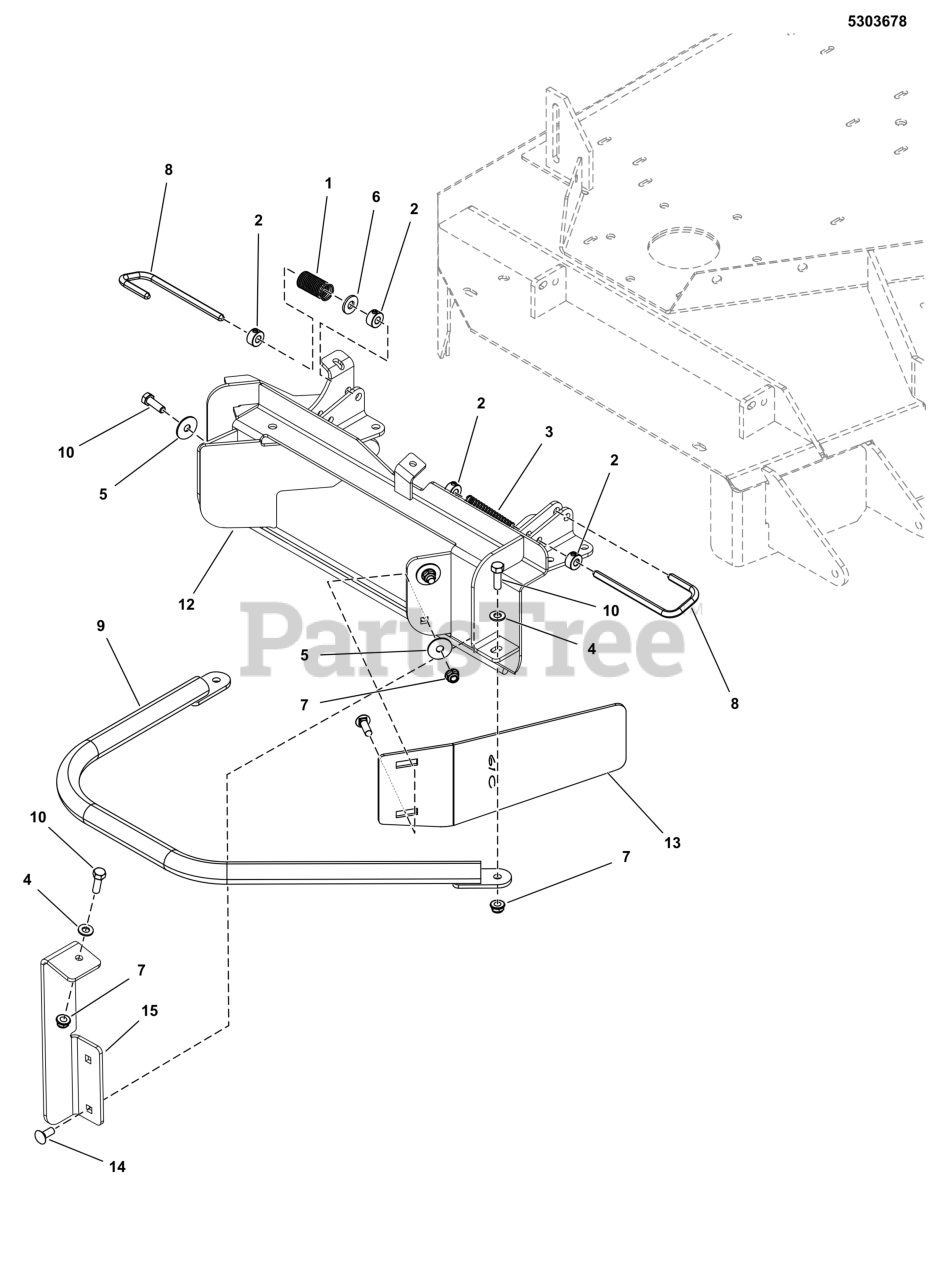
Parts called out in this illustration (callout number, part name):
1	SPRING-COMP 0.880ODX 02.187LG .062WIRE
1	SPRING-COMP, .375IDX2.75LGX.054WR, SS
2	COLLAR, 5/16 SET
3	SPRING-COMP, .375IDX2.75LGX.054WR, SS
4	WASHER, 5/16" SAE
5	WASHER, 5/16 FENDER
6	WASHER, 5/16 USS
7	NUT, 5/16-18 HEX NYLOCK FLANGE
8	ROD, LOCKING PIN, BLOWER
9	WELD, NERF BAR, 61" T-MAX - BLK
10	BOLT, 5/16-18 X 1 GD5 CZ
11	BOLT, 5/16-18 X 1, CARRIAGE
12	WELD, ADAPTER, 61" COM - BLK
12	WELD, ADAPTER, 61" TMAX-BLK
13	BAFFLE, Front
14	BOLT, 5/16-18 X 3/4, CARRIAGE, GD5, CZ
15	BRACKET, PLATE SUPPORT, TMAX-BLK
